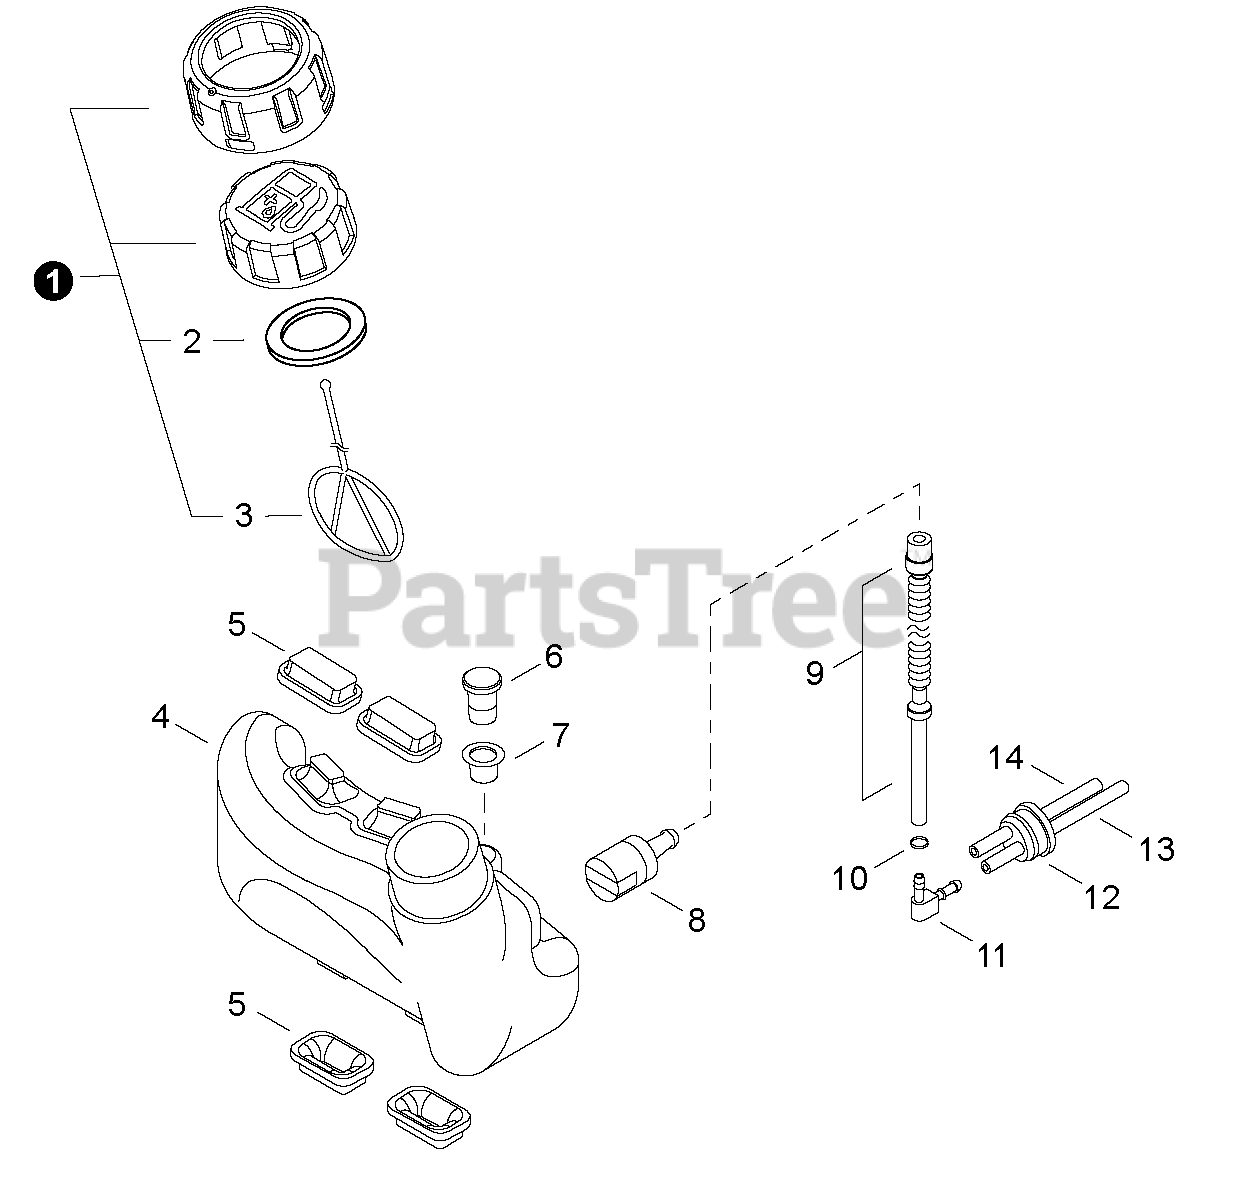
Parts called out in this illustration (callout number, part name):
1	CAP ASSY, FUEL
2	GASKET, FUEL CAP
3	CONNECTOR, CAP L= 123
4	TANK, FUEL
5	CUSHION
6	VENT ASSY
7	GROMMET, FUEL
8	FILTER, FUEL
9	PIPE, FUEL
10	CLIP Ø6.5 MM
11	CONNECTOR, PIPE
12	GROMMET, FUEL
13	PIPE, FUEL 3×5×83 BLACK
14	PIPE, FUEL 3×6×85 CLEAR
